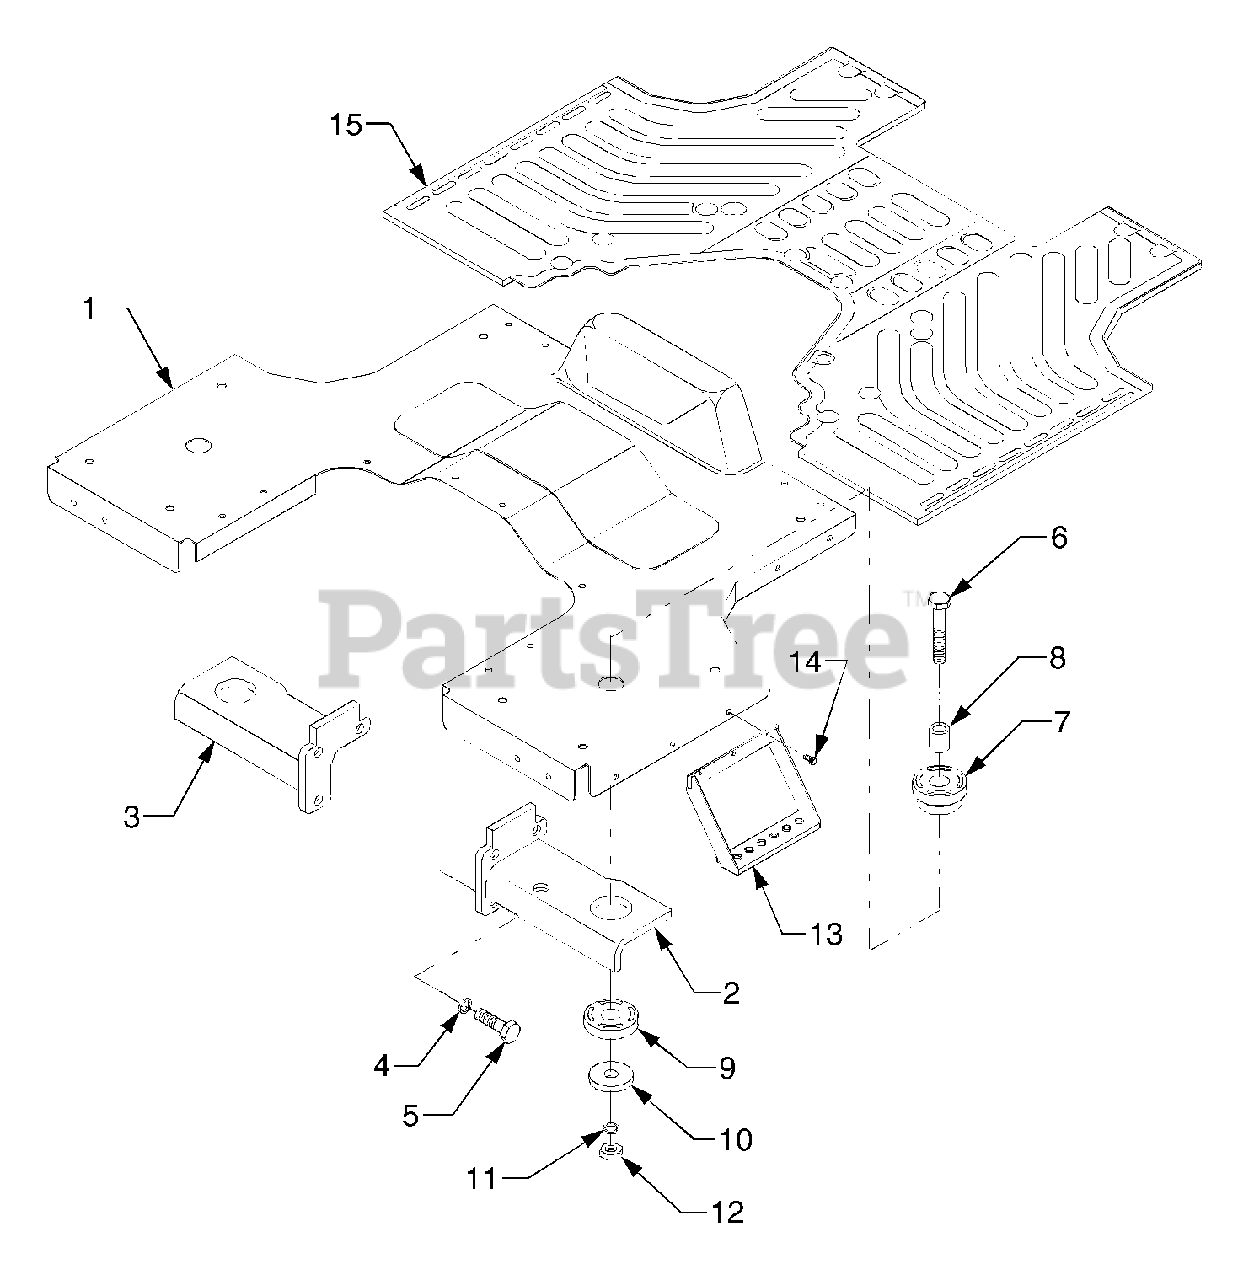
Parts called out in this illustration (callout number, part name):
2	Support, Step (LH)
3	Support, Step (RH)
4	Washer, Spring
7	Rubber, Cabin Cushion (A)
8	Collar, Cabin Cushion (A)
9	Rubber, Cabin Cushion (B)
11	Washer, Spring
13	Step
